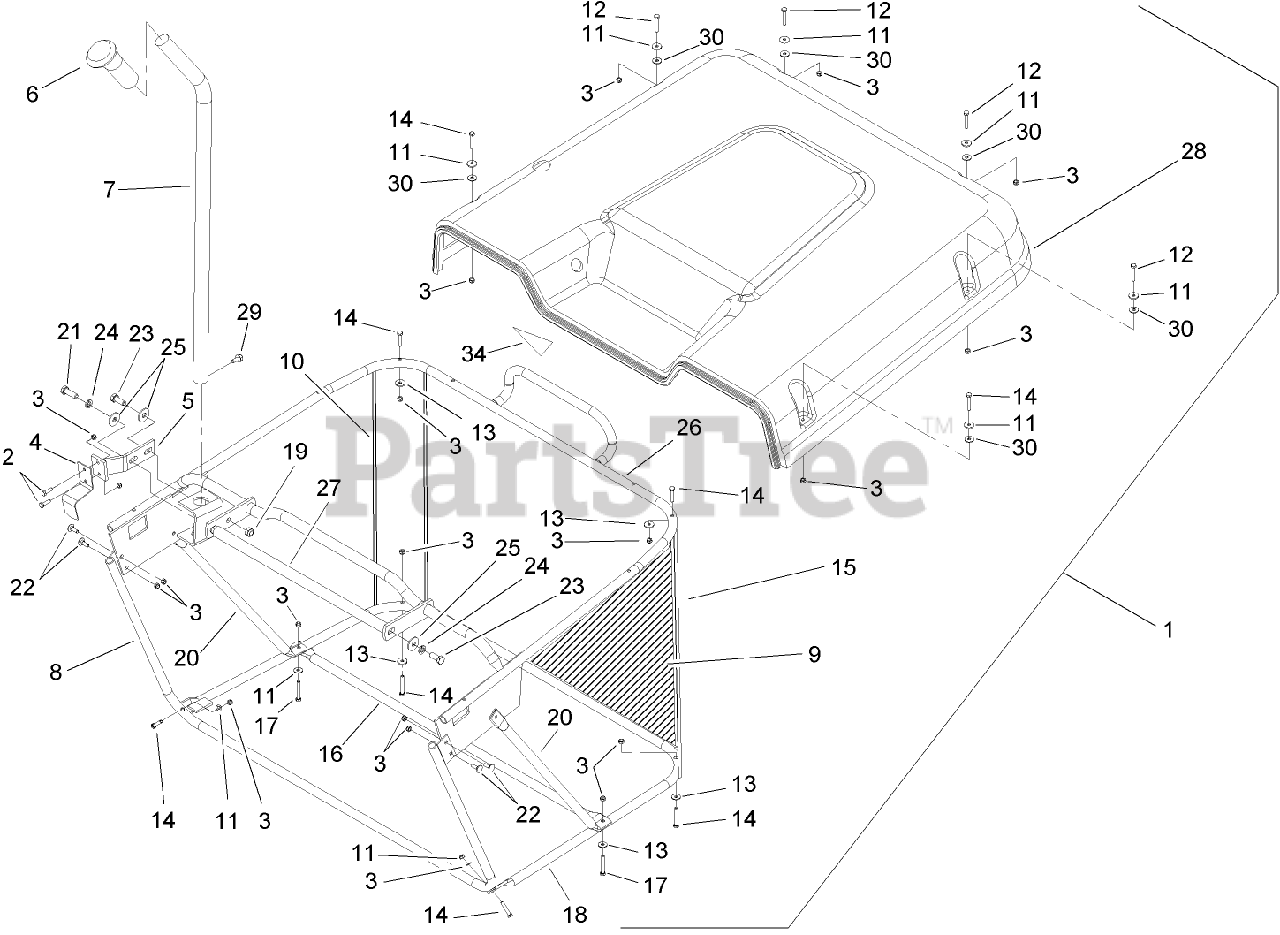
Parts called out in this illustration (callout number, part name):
2	SCREW-HH
3	NUT-LOCK
4	SPRING-COLL, INTERLOCK SWITCH
5	Bracket-Spring
6	GRIP-HANDLE
7	LEVER-DUMP
8	FRONT FRAME ASM
9	BAG-GRASS
10	SUPPORT-CORNER, RIGHT
11	WASHER-FLAT
13	WASHER
14	SCREW-HEX
15	SUPPORT-CORNER, LEFT
16	BRACE-CONNECTING
17	SCREW-HEX
18	BOTTOM FRAME ASM
19	NUT-LOCK, NI
21	SCREW-HH
22	BOLT-CARRIAGE
23	SCREW-HH
25	WASHER-PLAIN
26	TOP FRAME ASM
27	HANDLE-LIFT
28	Cover-Collector
30	WASHER-RUBBER
34	DECAL-BAG TO FRAME
